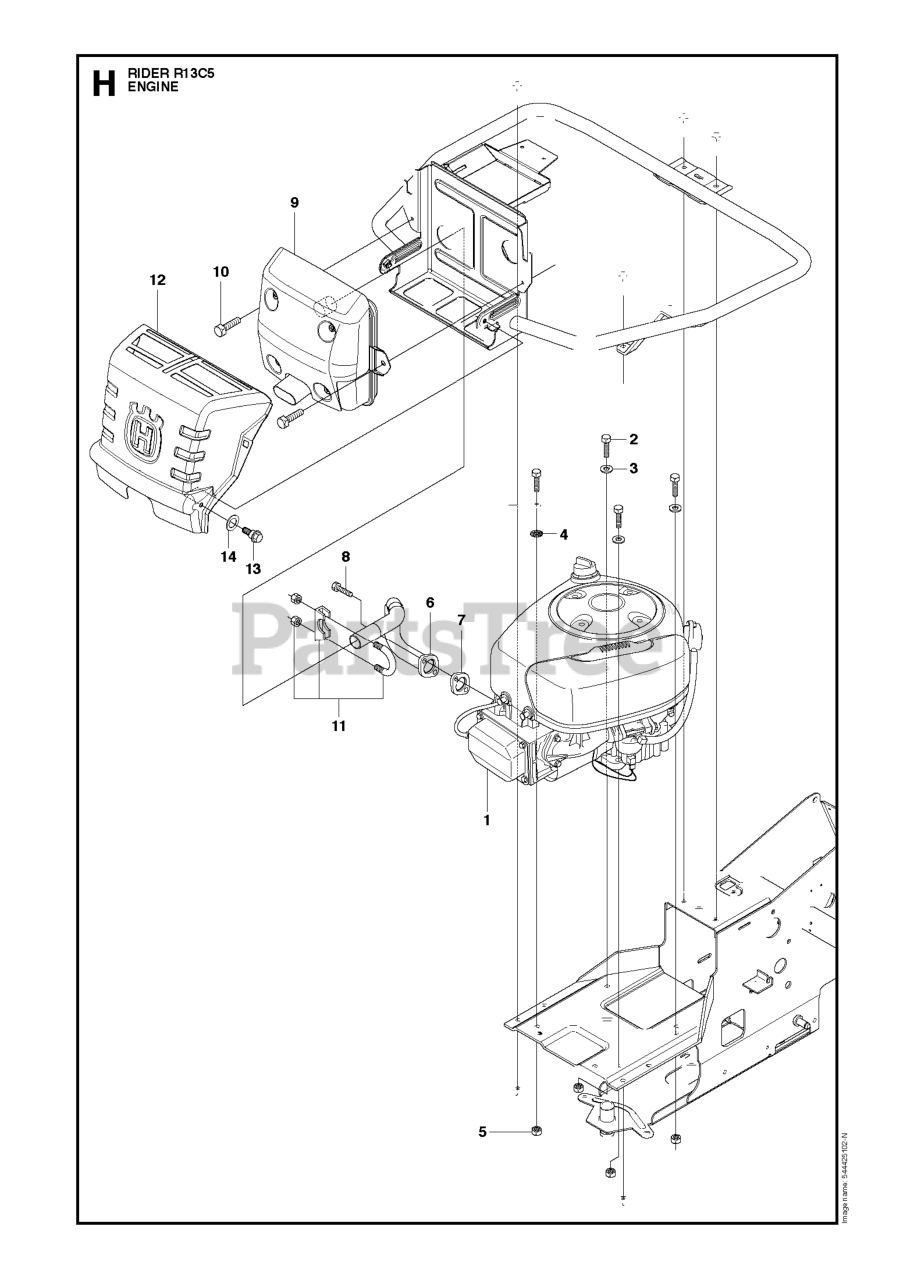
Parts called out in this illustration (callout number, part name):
3	WASHER BRB 8.4X17
5	LOCKNUT M8
6	EXHAUST PIPE ASSY
9	MUFFLER ASSY
11	CLAMP
12	HEAT PROTECTOR
14	SPRINGWASHER
